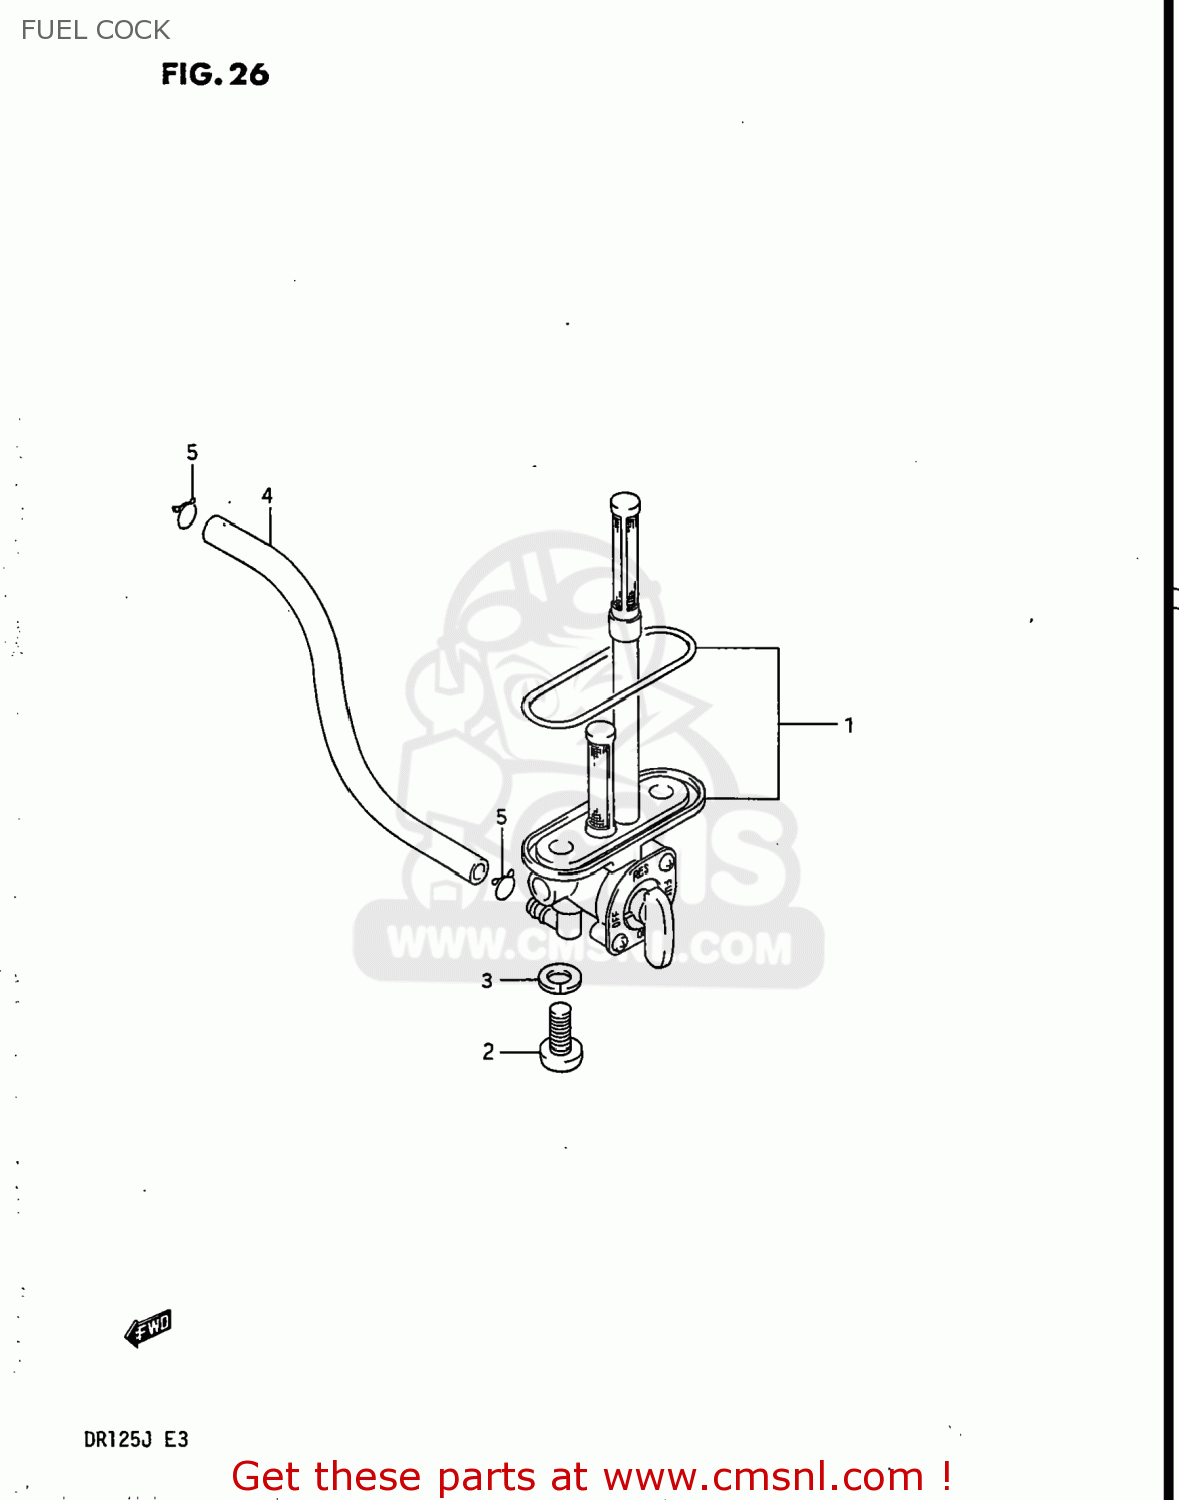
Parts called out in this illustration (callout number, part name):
1	COCK ASSY,FUEL
2	SCREW
3	WASHER,LOCK
4	HOSE
5	CLIP
